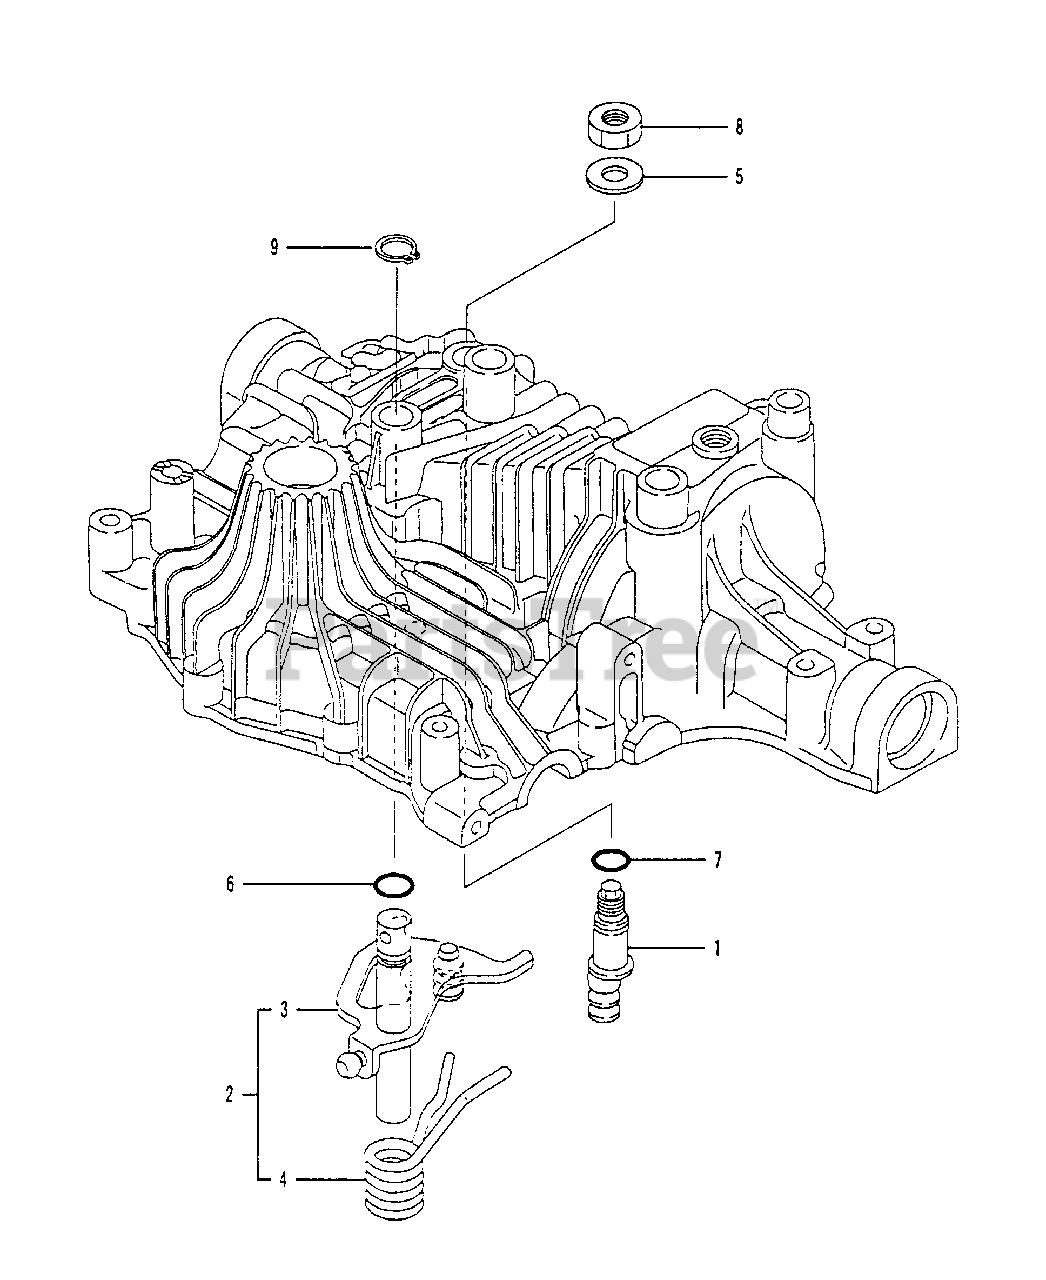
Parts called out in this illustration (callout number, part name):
1	FULCRUM (ECCENTRICITY
2	CONTROL SHAFT CMP
3	CONTROL SHAFT
4	SPRING (TORSION
6	PACKING P 12
7	PACKING P 10A
